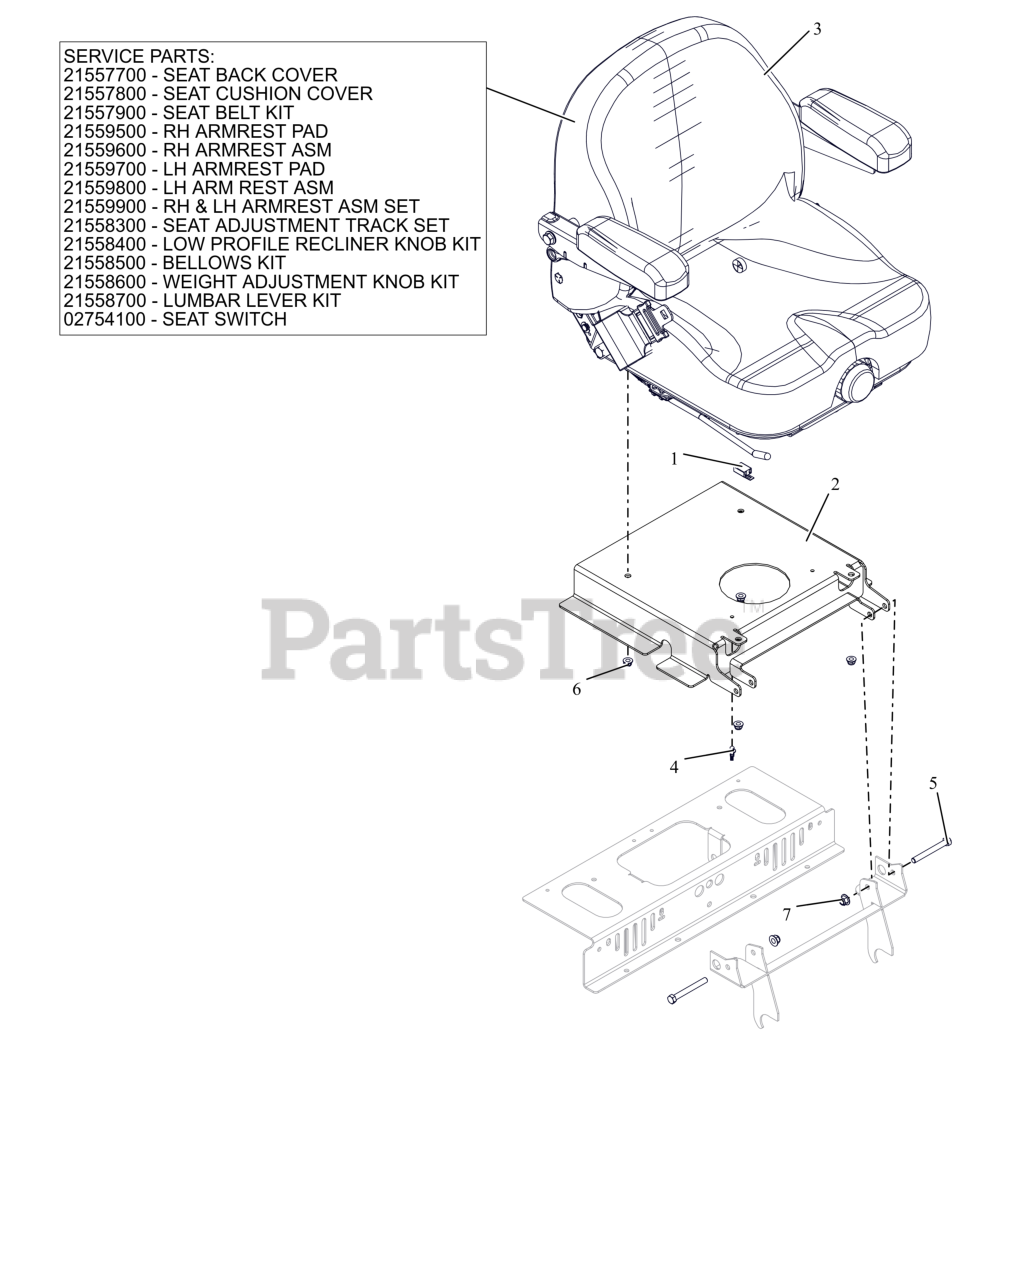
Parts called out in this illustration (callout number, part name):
1	HARNESS, PT200 SEAT ADAPTER
2	WLDMT, SEAT PLATE (RED)
3	SEAT, FULL SUSPENSION
3	COVER, SEAT BACK
3	COVER,SEAT CUSHION
3	KIT, SEAT BELT
3	PAD, RH ARMREST
3	ASM, RH ARMREST
3	PAD, LH ARMREST
3	ASM LH ARMREST
3	SET, RH & LH ARMREST ASM
3	SET, SEAT ADJUSTMENT TRACK
3	KIT, LOW PROFILE RECLINER KNOB
3	KIT, BELLOWS
3	KIT, WEIGHT ADJUSTMENT KNOB
3	KIT, LUMBAR LEVER
3	SWITCH- SNAP MTG N.O.
4	CABLE TIE W/ TREE (.25 HOLE)
5	BLT, HEX .38-16X3.25 G5 ZCC
6	NUT,NYL-FLG .31-18 GF ZCC
7	NUT,NYL-FLG .38-16 GF ZCC
